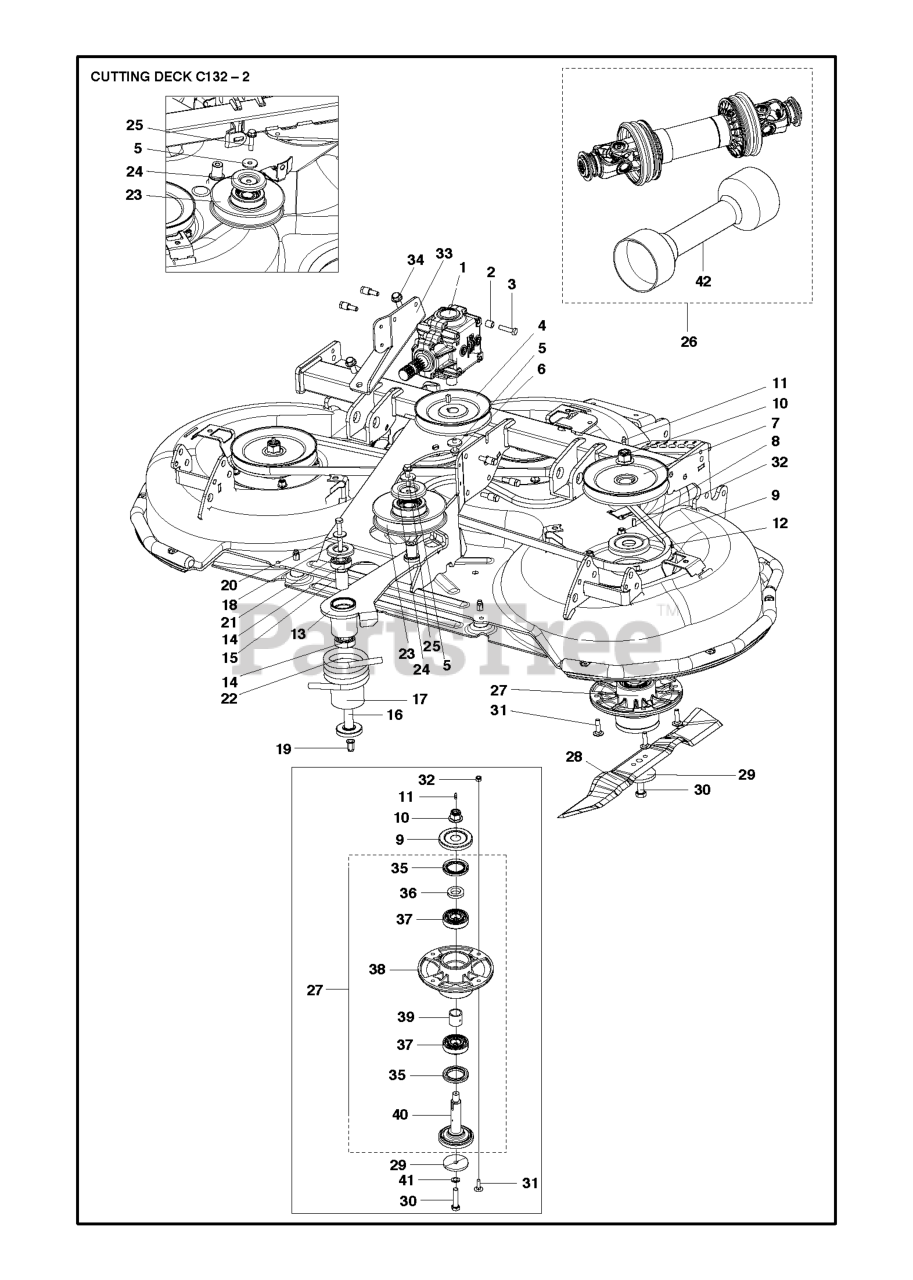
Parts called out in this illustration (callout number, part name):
11	GREASE NIPPLE
14	BALL BEARING
17	SPACER, IDLER PIVOT
19	BLIND RIVET NUT
21	DUST SHIELD
25	SCREW EHHFM
28	BLADE REAR DISCHARGE/MULCH C13
32	NUT FLANGE
37	BALL BEARING 6305 C3
